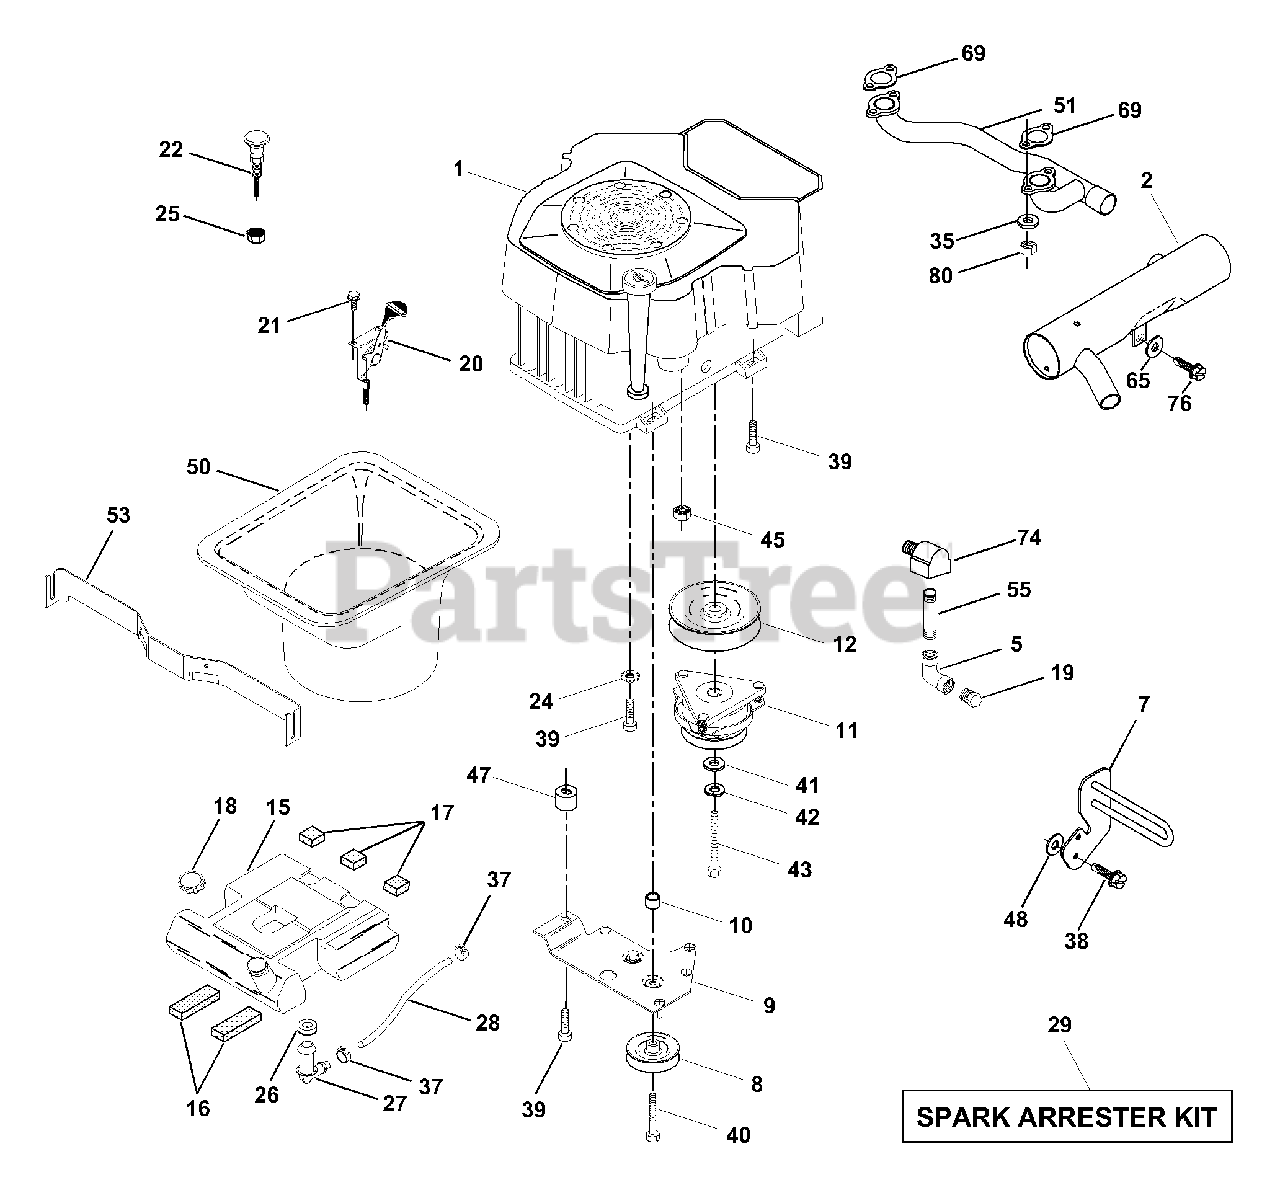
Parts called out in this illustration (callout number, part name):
2	Muffler Side
5	Elbow STD 90 Degree 3/8 - 18 NPT
7	Muffler Assembly Guard
8	Pulley V-Idler
9	Keeper Asm. Belt Engine VGT
10	Bushing
11	Clutch Electric
12	Pulley Engine VGT Elect Clutch
15	Tank Fuel Rear 3.50
16	Pad Spacer
17	Pad Spacer
18	Cap Asm Fuel W/Sym Vented
19	Plug Oil Drain
20	Control Throttle
21	Screw Hex Thd Cut 1/4-20 X 5/8
22	Control Choke
24	Washer Ext Tooth 3/8
25	Nut Keps 3/8-24 Unf
26	Bushing
27	Stem Tank Fuel
29	Spark Arrester Kit
35	Washer
37	Clamp Hose
38	Screw 3/8-16 x 1-1/4
39	Screw TT 3/8-16 x 2-1/4 UNC
40	Screw TT 3/8-16 x 4 UNC
41	Washer 1-1/2 OD X 15/32 ID X .250
42	Washer Lock 7/16
43	Bolt Hex 7/16-20 X 4-1/4 Ga 5
45	Nut Keps Hex 1/4-20
47	Spacer Engine CV22 Round PM
48	Washer 13/32 x 1-1/4 x 7 Ga.
50	Duct Air Intake
51	Manifold VGT
53	Rod Support Hood Duct
55	Nipple, Pipe 4-1/2
65	Washer 13/32 x 1 x 14 Ga.
69	Gasket
74	Elbow Street Brass
76	Screw Hexwsh Thdrol 3/8-16 x 3/4
80	Nut Flange M8-1.25
